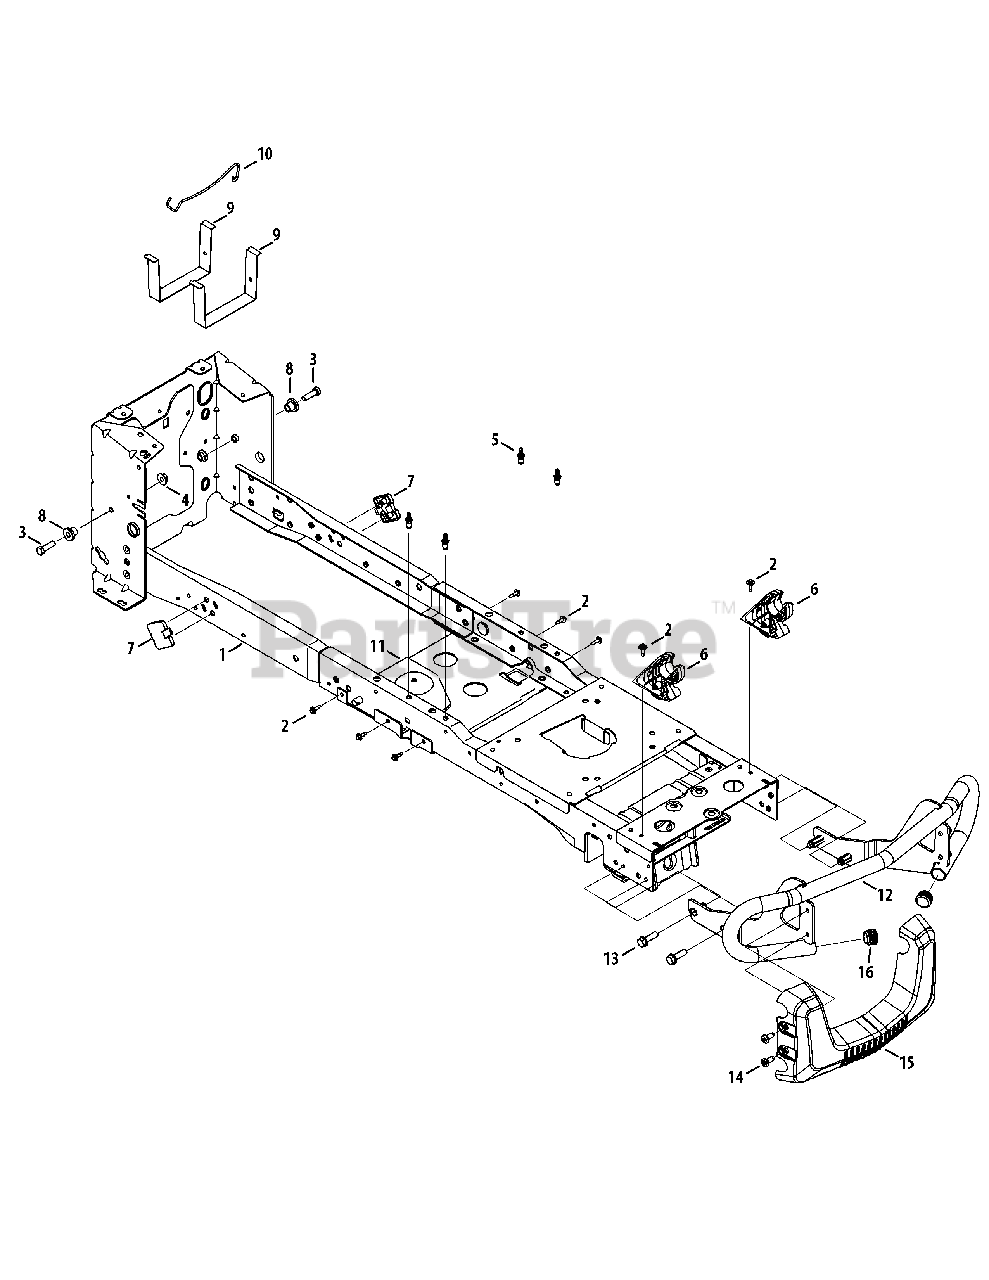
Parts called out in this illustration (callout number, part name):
1	Frame Assembly
2	Screw, M6-1 x .625
3	Hex Cap Screw, 3/8-16 x 1.25
4	Flange Lock Nut, 3/8-16
5	Rivet, 1/4-20 x .750
6	Pivot Bracket
7	Wear Pad
8	Shoulder Spacer, .38 x 1.0 x .70
9	Battery Bracket
10	Rod, Battery
12	Bumper Assenbly
13	Hex Flange Screw, 3/8-16
14	Self Tapping Screw, 5/16-18 x .75
15	Bumper
16	Hub Cap
